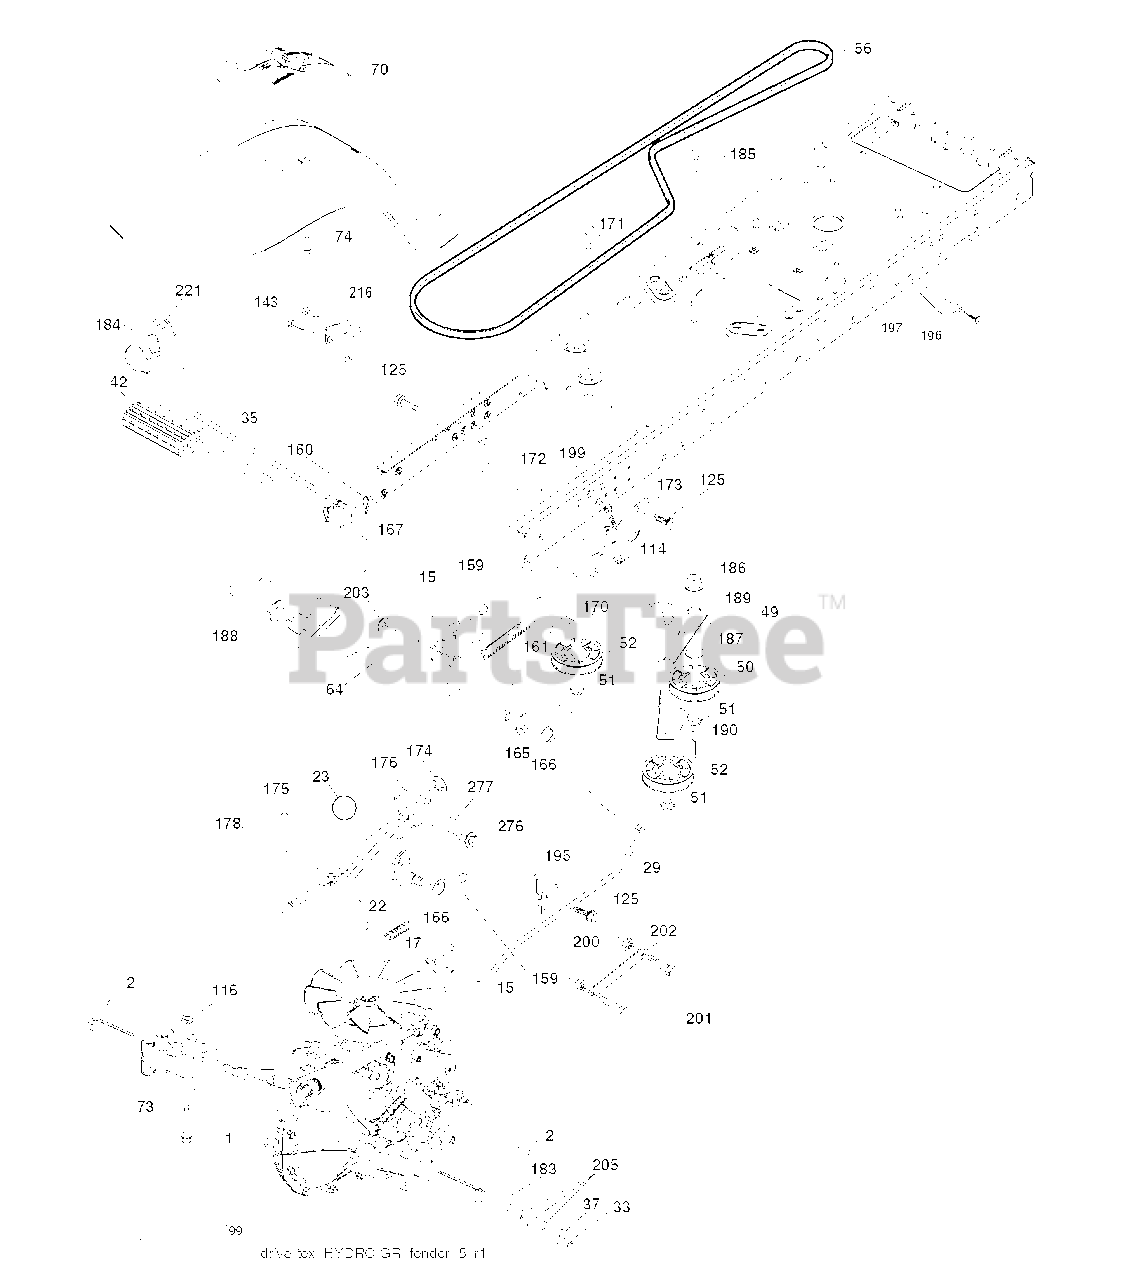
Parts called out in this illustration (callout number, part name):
2	SQUARE KEY
17	SPRING.BRAKE.HG3000/3500
22	ROD.SHIFT.FENDER.STGT.
23	PISTOL KNOB
29	ROD.BRAKE.HG-0510
33	E-RING LT
35	ROD.BRAKE.PARKING.GT.H
42	PEDAL COVER T
49	BOLT
50	IDLER.FLAT.910.OFFSET
51	NUT LOCK FLG 3/8-16 UNC
52	IDLER.V-GROOVE.910.OFFSET
64	SHAFT.ASM.PEDAL.BRAKE.
73	BOLT HEX 5/16-18 GR 5
74	SCREW.HI-LO.CONSOLE
99	ROD.ASM.BYPASS.0510.HYDRO.LT
114	NUT.71038.31-18.HEX.NYLOCK
116	NUT LOCK HEX FLANGE 5/16-18
125	SCREW
159	COTTER PIN
160	RETAINER CLIP
161	SPRING, RETURN LT
165	BUSHING.SHAFT.BRAKE.HAND
166	NUT.PUSH.625.2006
167	LATCH.BRAKE.SPRING
170	KEEPER.V-IDLER.CENTER.
171	BOLT
172	STRAP.TRQ.LH.FS.HG0510
173	STRAP TORQUE RH
174	NUT.PUSH.500.2006
175	SHAFT.ASM.SHFT.HG0510/
176	ARM.CLEVIS.ROD.SHIFT
178	SPRING.SHIFT.GT2006
183	SPACER AXLE
184	HANDLE.PARKG.BRK.HUSQ/
186	SPACER.RETAINER
187	WASHER 12/32X2X10GA
188	LINK.CLUTCH.GROUND.DRIVE
189	BELLCRANK.GROUND.DRIVE.TEX.
190	KEEPER.BELLCRANK.DRIVE
195	BRKT.ROD.BRAKE.18/20/2
197	LINK.CLUTCH.ANIT-ROTAT
199	BOLT
200	NUT.CENTERLOCK.5/16-
201	BOLT SHOULDER 5/16-18 UNC
203	WASHER
216	BRACKET.PULLEY.IDLER.W/TEX
221	RETAINER.SPRING.CLIP.H
276	BOLT FIN HEX 7/16-14 X 1
277	WASHER SERRATED
